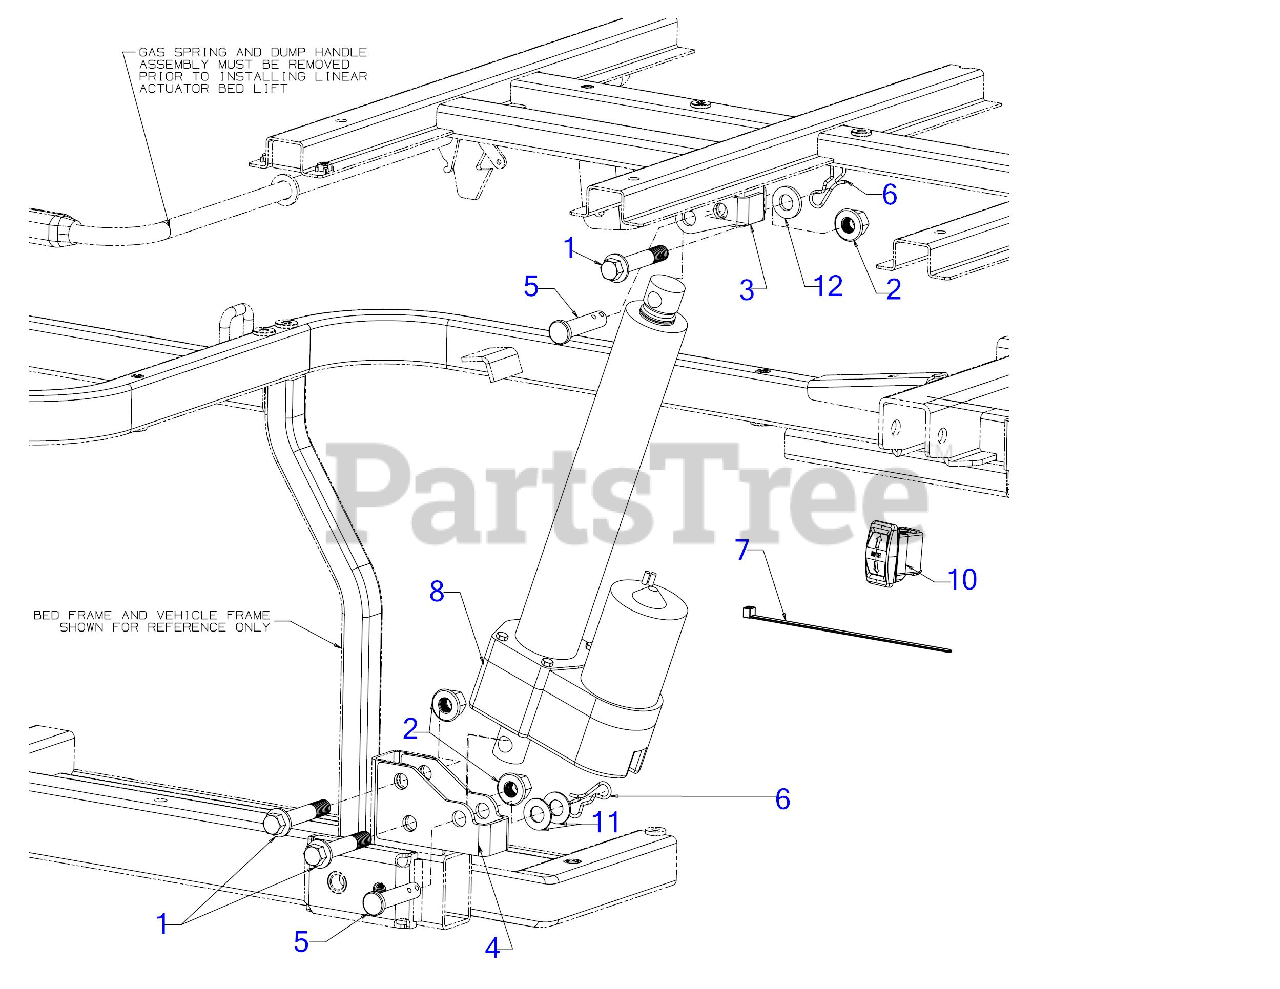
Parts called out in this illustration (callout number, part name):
1	HEX HEAD BOLT M12X1.25-65
2	LOCK NUT M12-1.25
5	CLEVIS PIN .50 x 2.0
6	BOW TIE COTTER PIN
7	7" CABLE TIE
8	ELECTRIC ACTUATOR
10	ROCKER SWITCH
11	FLAT WASHER .510 x 1.00 x .060
12	FLAT WASHER .510 x 1.000 x .125
